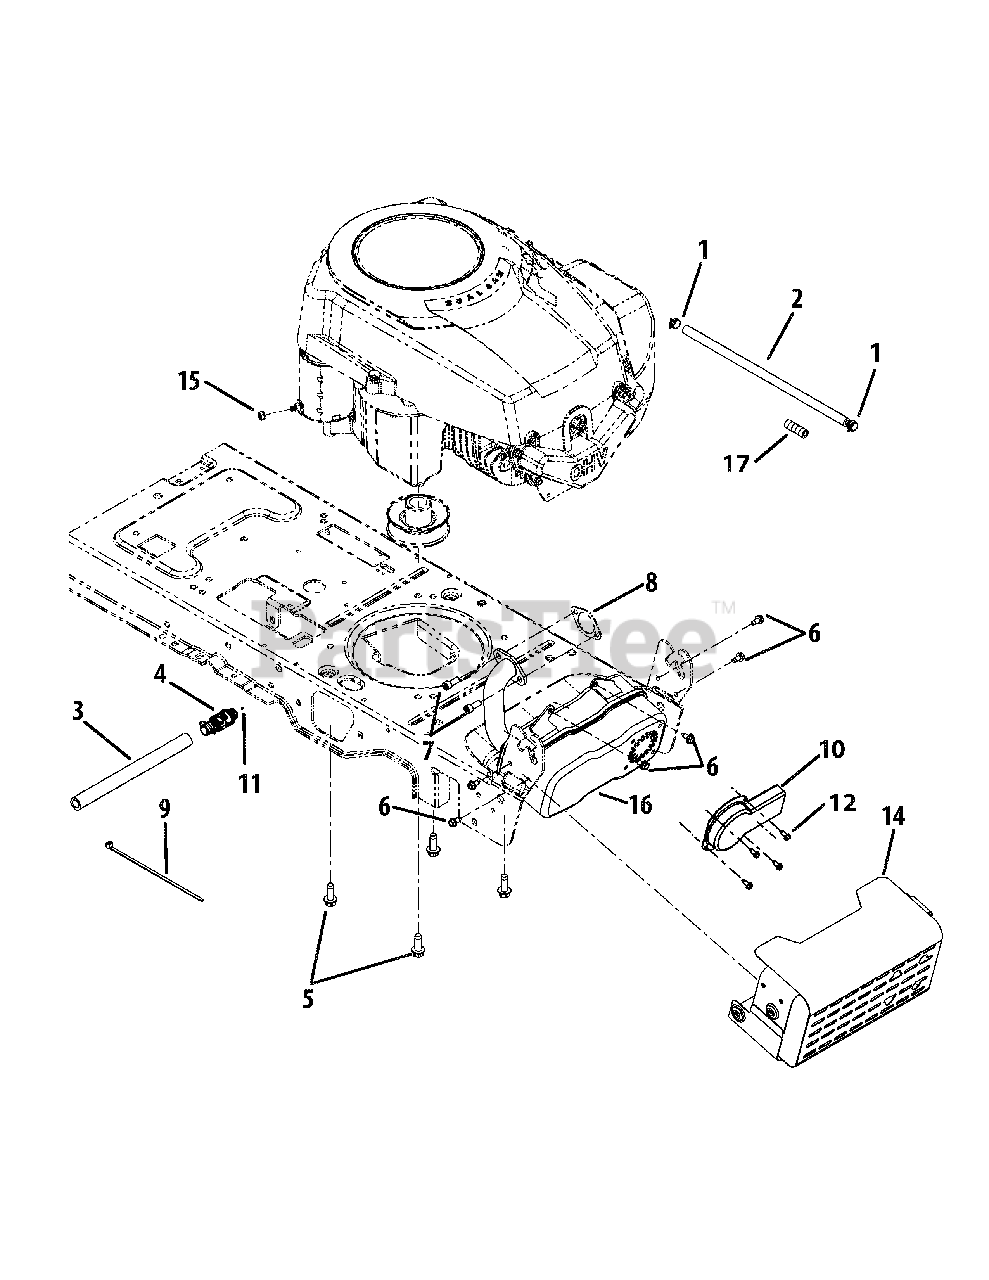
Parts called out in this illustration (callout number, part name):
1	Hose Clamp
2	Fuel Line 16" Lg.
3	Oil Drain Hose
4	Oil Drain
5	TT Screw 3/8-16 x 1.00
6	Hex Wash S-Tapp Screw 1/4-20 x .50
7	Screw. 5/16-18 x .75
8	Exhaust Gasket
9	Cable Tie
10	Long Muffler Deflector
11	Pipe Sealant (puchase locally)
12	Hex AB Screw #8-18 x .50
15	Hex Sems Nut 1/4-20
16	Muffler
17	Vent Hose (optional)
